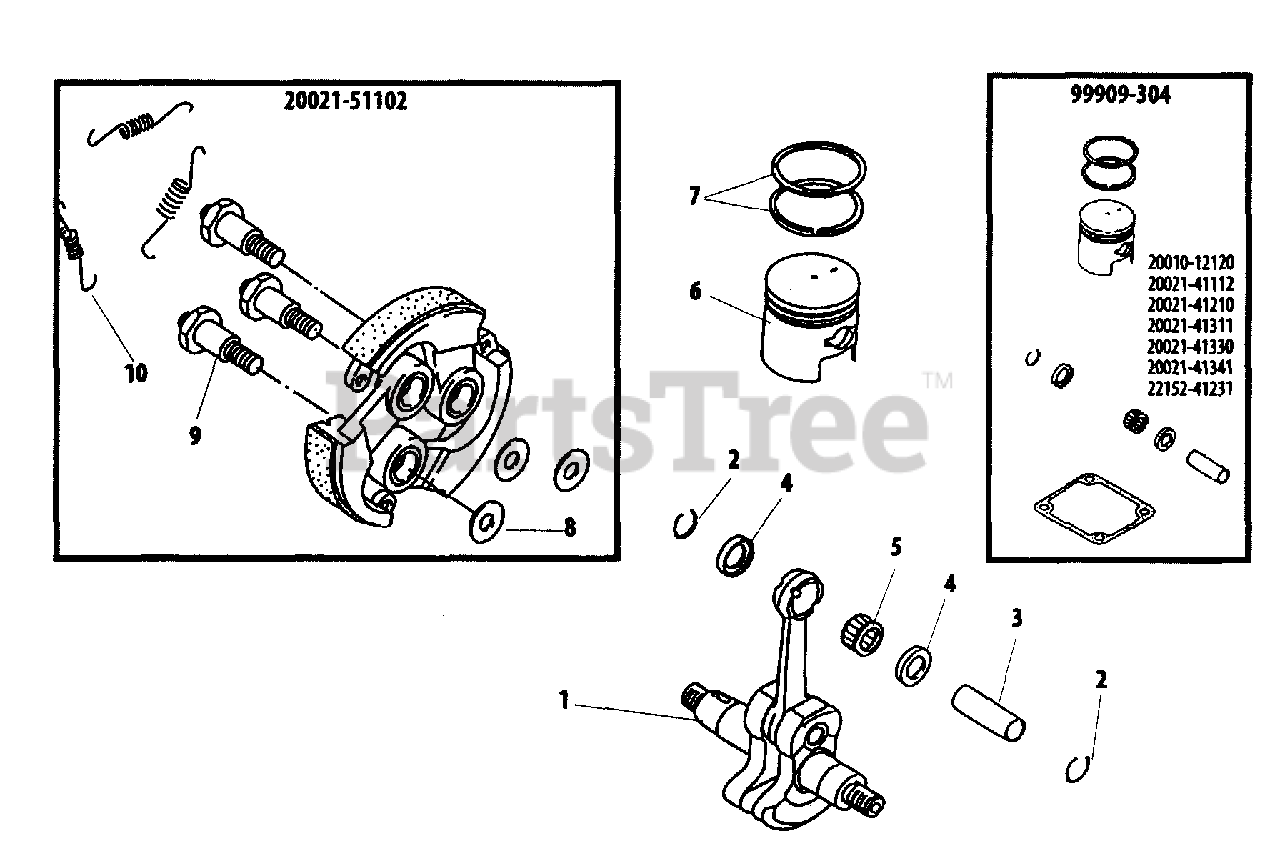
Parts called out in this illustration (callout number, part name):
1	CRANKSHAFT ASSY
2	RING, RETAINING
3	PIN, PISTON
4	WASHER
5	BEARING, NEEDLE
6	PISTON
7	RING, PISTON
8	WASHER - 6
9	BOLT, CLUTCH
10	SPRING, CLUTCH
20021-51102	CLUTCH SHOE ASSY
99909-304	PISTON ASSY
